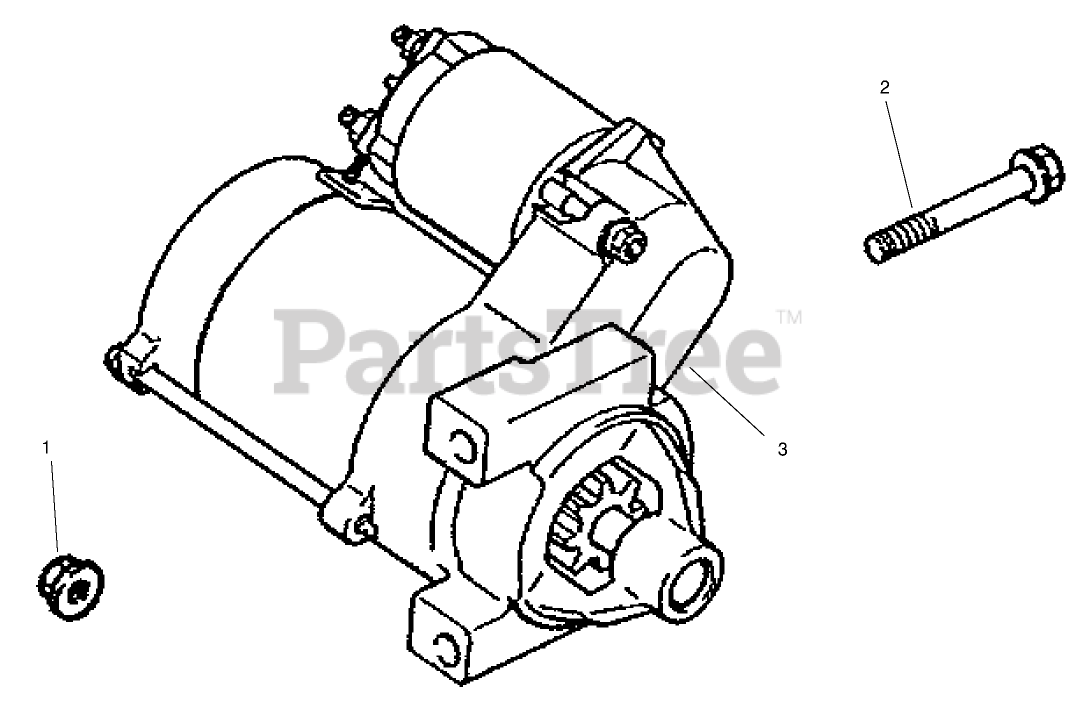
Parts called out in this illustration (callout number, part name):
1	NUT-FLANGE (M8X1.25)
2	SCREW-FLG (M8X1.25X80)
3	STARTER ASM (SOLENOID SHIFT)
